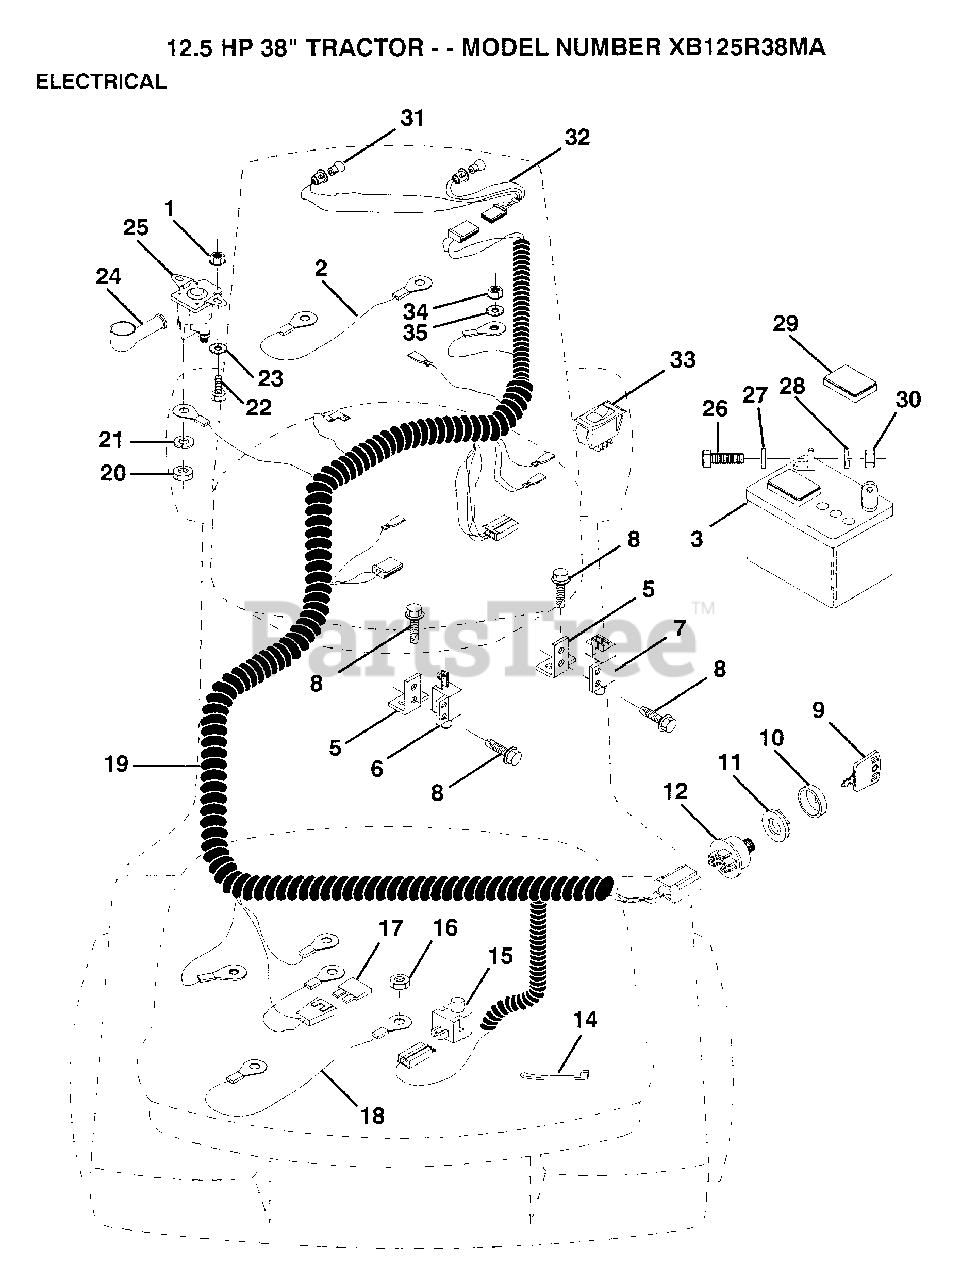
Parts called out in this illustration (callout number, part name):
1	NUT
2	CABLE ASM.
5	BRACKET LT
6	SWITCH-INTER. GT
7	SWITCH INTERLOCKT
8	SCREW
9	KEY
11	NUT IGNITION
15	SWITCH SEAT
17	FUSE HYT
18	CABLE ASSY
20	NUT
22	BOLT
26	BOLT LT
27	WASHER
28	LOCKWASHER
29	"CAP,BATTERY "
33	SWITCH LT
34	NUT
35	LOCKWASHER
